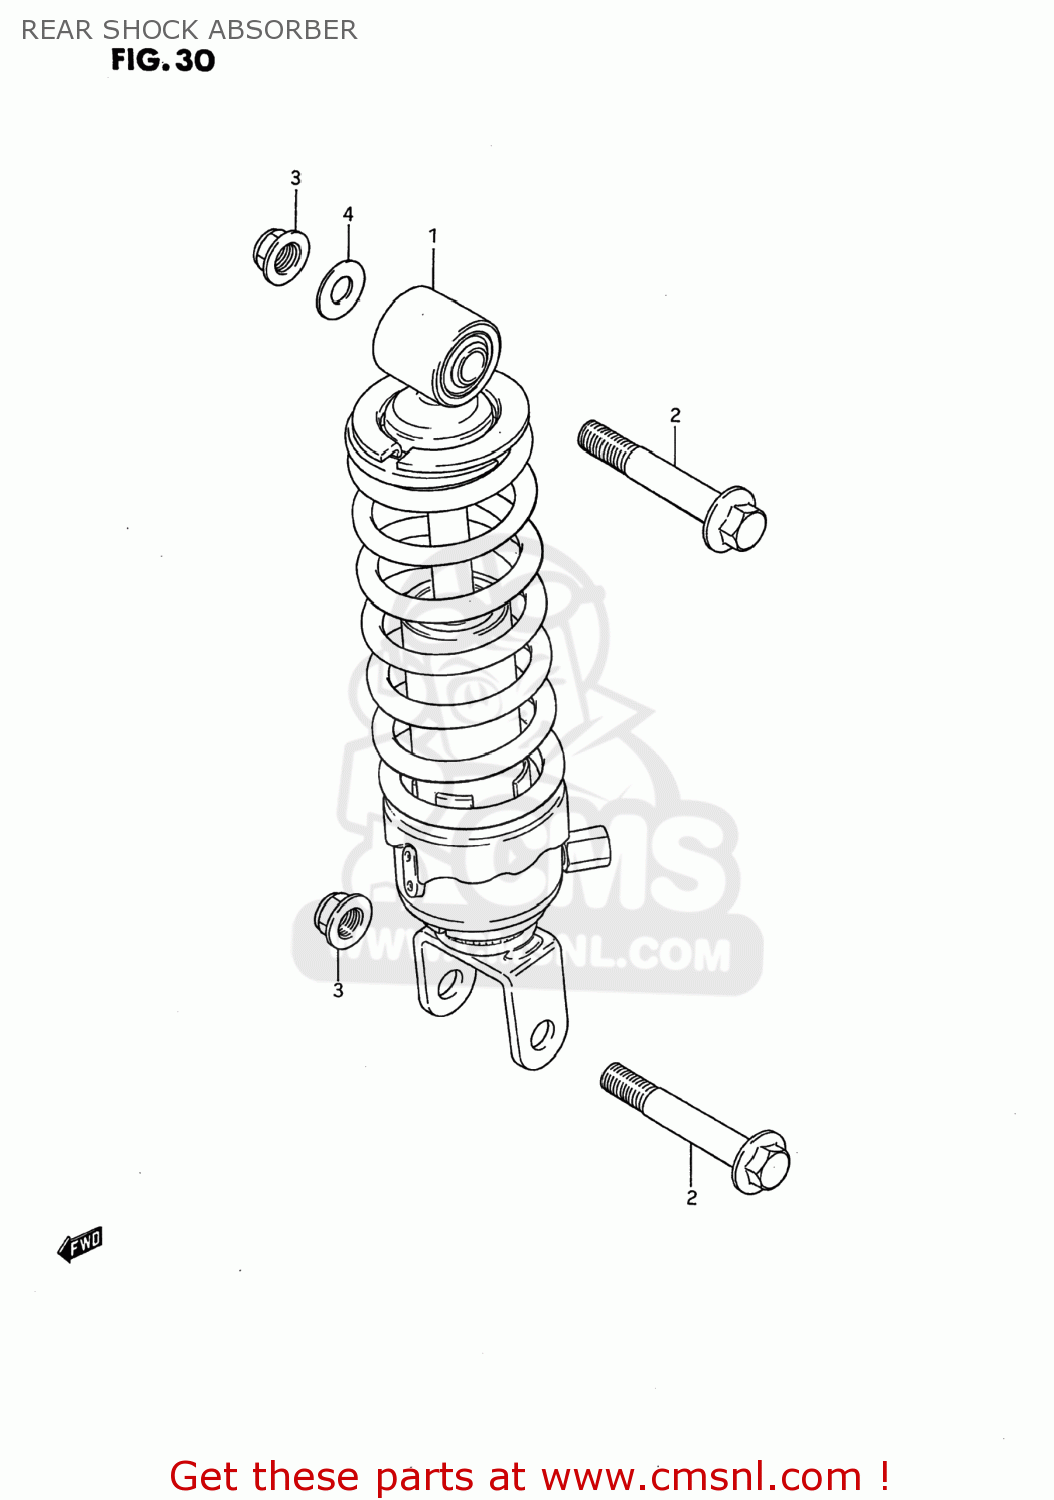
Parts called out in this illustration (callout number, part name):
1	ABSORBER ASSY,RR SHOCK
2	BOLT,RR SHOCK ABSORBER(10X51)
3	NUT
4	WASHER
